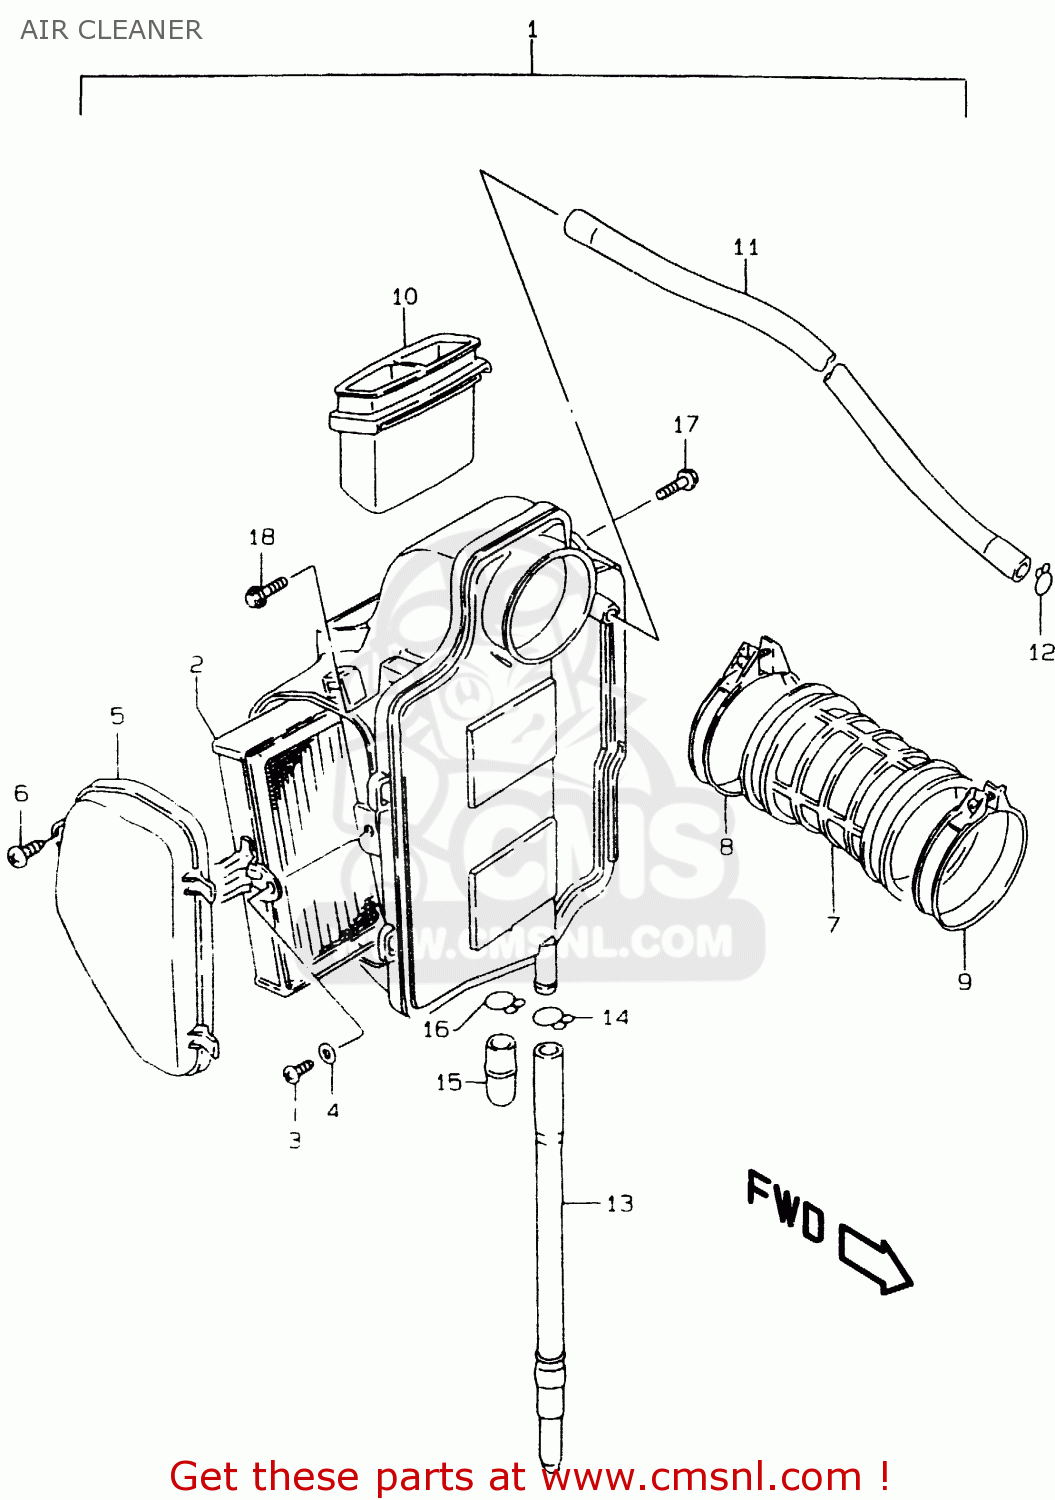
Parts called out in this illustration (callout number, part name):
1	CLEANER ASSY,AIR
2	FILTER ASSY,AIR
3	SCREW
4	WASHER,LOCK
5	CAP,AIR CLEANER
6	SCREW 5X12
7	TUBE,AIR CLEANER OUTLET
8	CLAMP
9	CLAMP
10	TUBE,INLET
11	HOSE(11X15X600)
12	CLIP
13	TUBE,DRAIN
14	CLIP
15	PLUG
16	CLIP
17	BOLT(6X16)
18	BOLT
